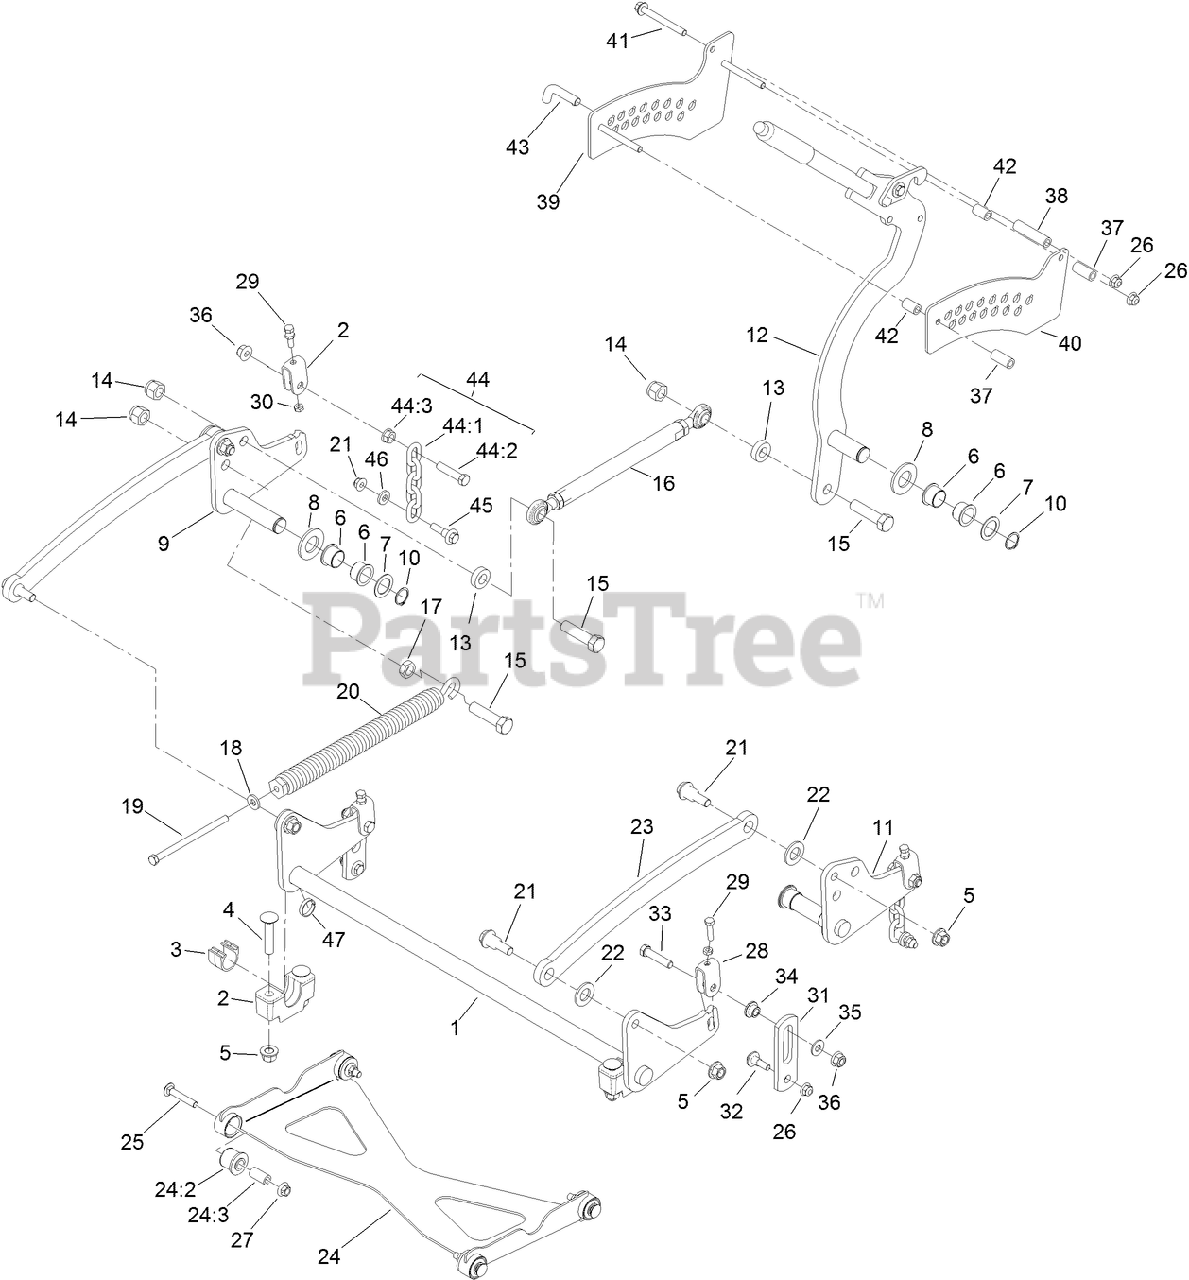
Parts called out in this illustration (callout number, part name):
1	SHAFT-CROSS, FRONT
2	SUPPORT-CROSS SHAFT, BEARING
3	BEARING-CROSS SHAFT, FRONT
4	BOLT-CARR
5	NUT-LOCK
6	BUSHING
8	WASHER-FLAT
9	ARM-LIFT, RH
10	RING-RETAINING
11	ARM-LIFT, LH
12	HOC LEVER ASM
13	WASHER
14	NUT-HEX, CENTER LOCK
15	SCREW-HH
16	HOC LINK ASM
17	NUT-JAM
18	WASHER-BELLEVILLE
19	BOLT-TAP, HH
20	SPRING-EXTENSION
21	SCREW-SHOULDER, HHF
22	WASHER-FLAT
23	LINK-LIFT
24:2	BUSHING-RUBBER, SUSPENSION
24:3	SPACER
25	SCREW-HH
26	NUT-HF, NI
27	NUT-HF
28	YOKE-ADJUST, DECK
29	SCREW-HH
30	NUT-JAM
31	LINK-LIFT
32	SCREW-SHOULDER, HHF
33	SCREW-HH
34	BUSHING-FLANGED
35	WASHER-FLAT
36	NUT-HF, NI
37	SPACER
38	SPACER-LONG
39	HOC PLATE AND DECAL ASM
40	PLATE-HOC, INNER
41	SCREW-HHF
42	SPACER
43	PIN-HOC
44	DECK LIFT CHAIN ASM
44:1	CHAIN-LIFT, DECK
44:2	SCREW-HH
44:3	NUT-HF
45	BOLT-SHOULDER
46	SPACER
47	SPACER-SPLIT
